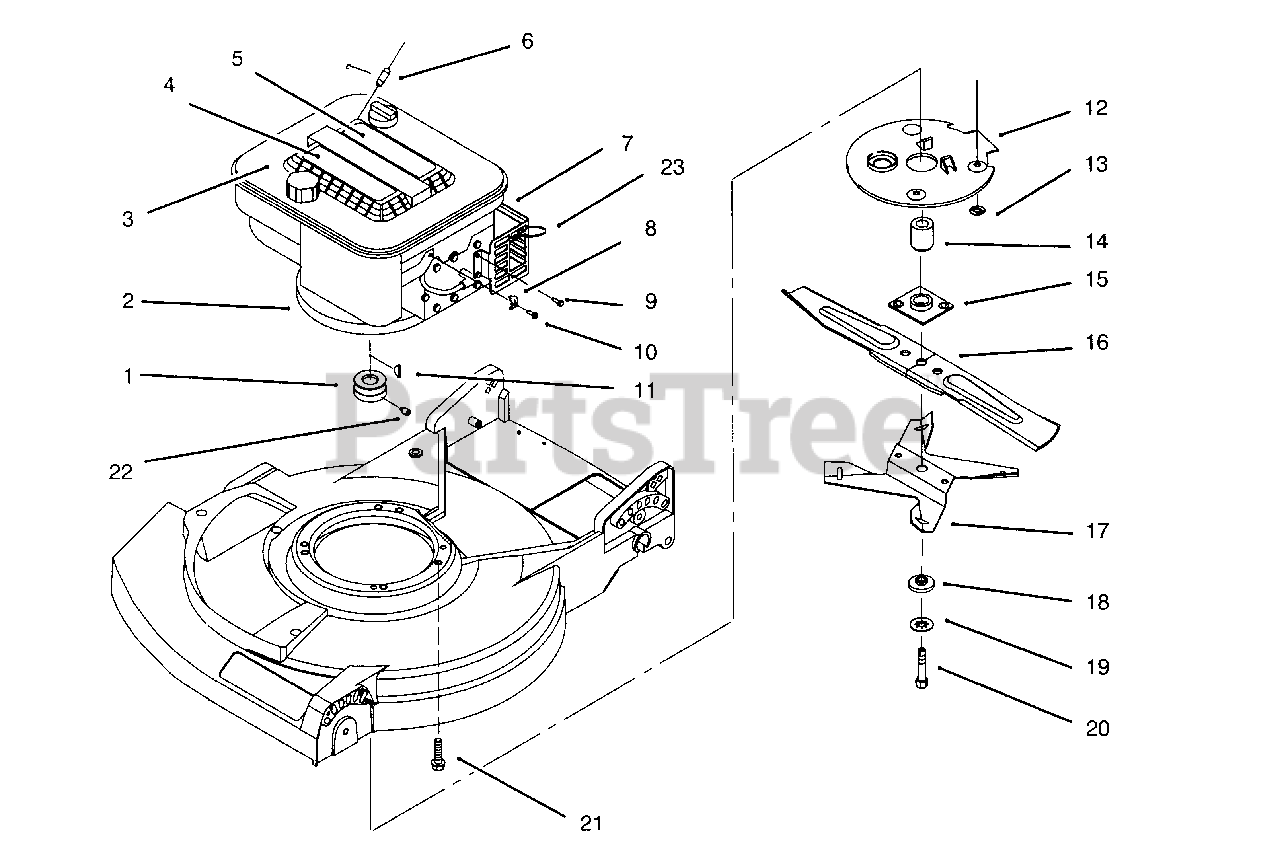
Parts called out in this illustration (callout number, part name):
1	Pulley-Engine (Model No. 10516 & 10521)
2	Engine
3	Grille-Engine
4	Decal-Recoil (Model No. 10416)
5	Decal-Recoil
6	Stop-Rope
7	Shield-Muffler
8	Clamp-Cable
9	Screw-Hex. Hd.
11	Key-Woodruff (Model No. 10421)
11	Key-Woodruff (Model No. 10516 & 10521)
12	Shield-Grass (Model No. 10516 & 10521)
13	Nut-Push (Model No. 10516 & 10521)
14	Hub-Blade Driver
15	Plate-Blade Driver
16	Blade-21"
17	Fan-Mulching
19	Washer-Lock
20	Bolt-Blade
21	Screw
22	Screw-Set (Model No. 10516 & 10521)
23	Strap-Tie
